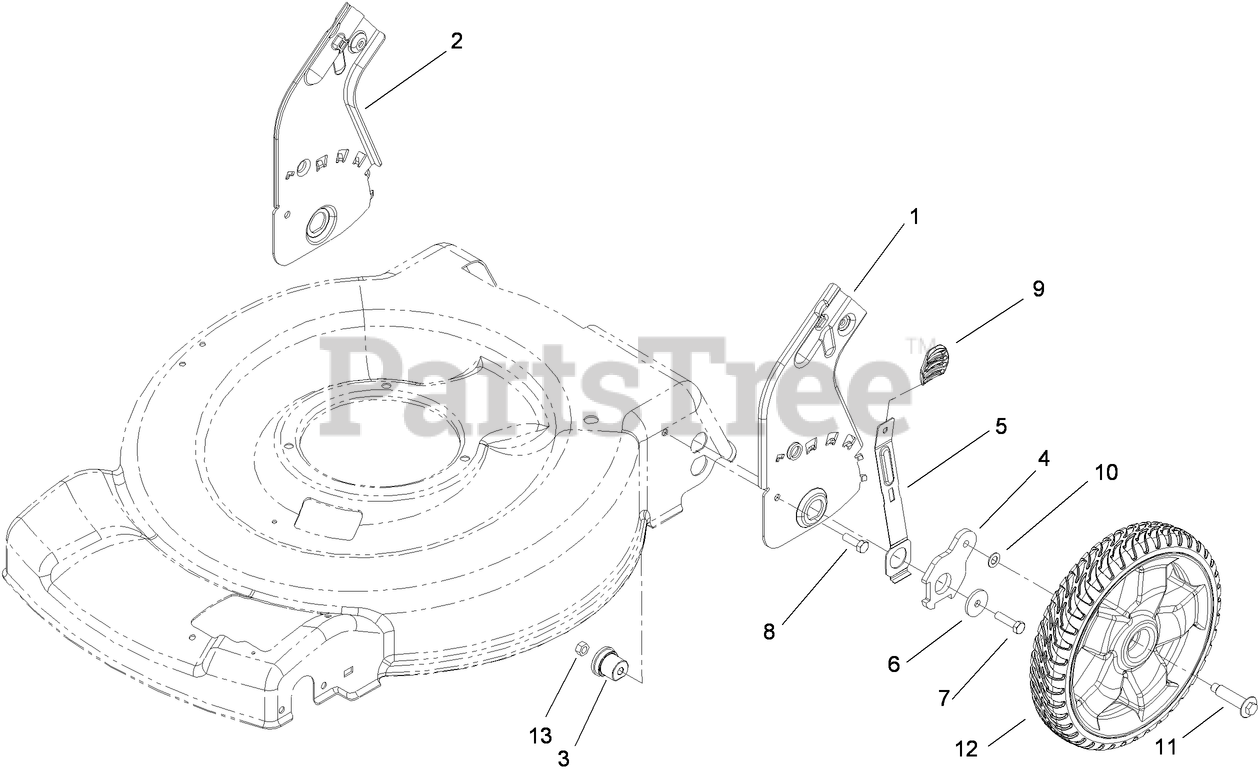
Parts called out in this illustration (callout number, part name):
1	PLATE-HOC, REAR (LH)
2	PLATE-HOC, REAR (RH)
3	BUSHING-MOUNT, HOC
5	ARM-SPRING, REAR
6	WASHER-FLAT
7	SCREW-HH
8	SCREW-HH
9	KNOB-LEVER, HOC
10	WASHER
11	BOLT-SHOULDER
13	NUT-LOCK, NI
